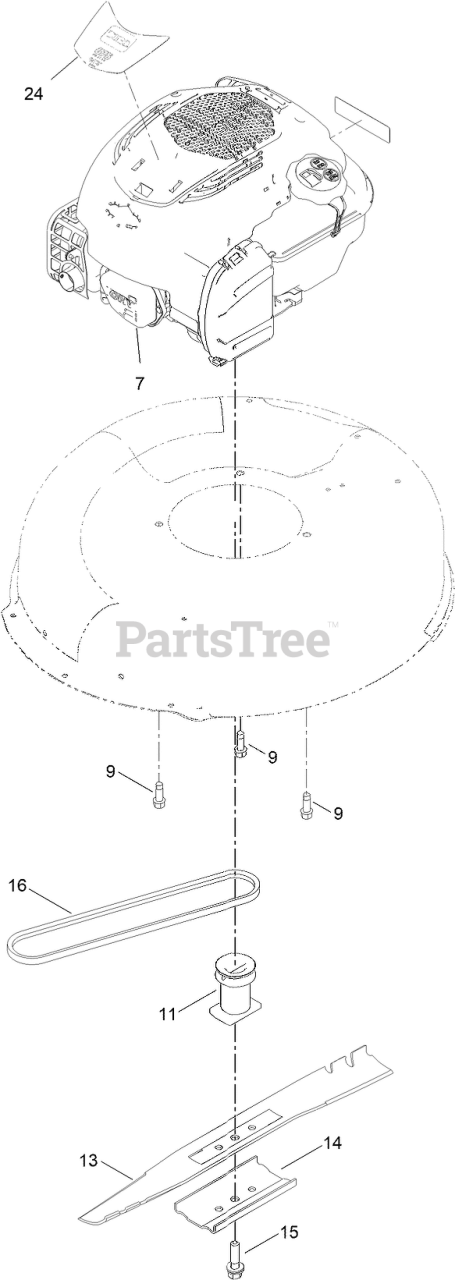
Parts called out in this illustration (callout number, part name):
9	SCREW-TAPTITE
11	DRIVER-BLADE
13	BLADE-21IN
14	SUPPORT-BLADE
15	BOLT-BLADE
16	V-BELT
24	DECAL-SHROUD
